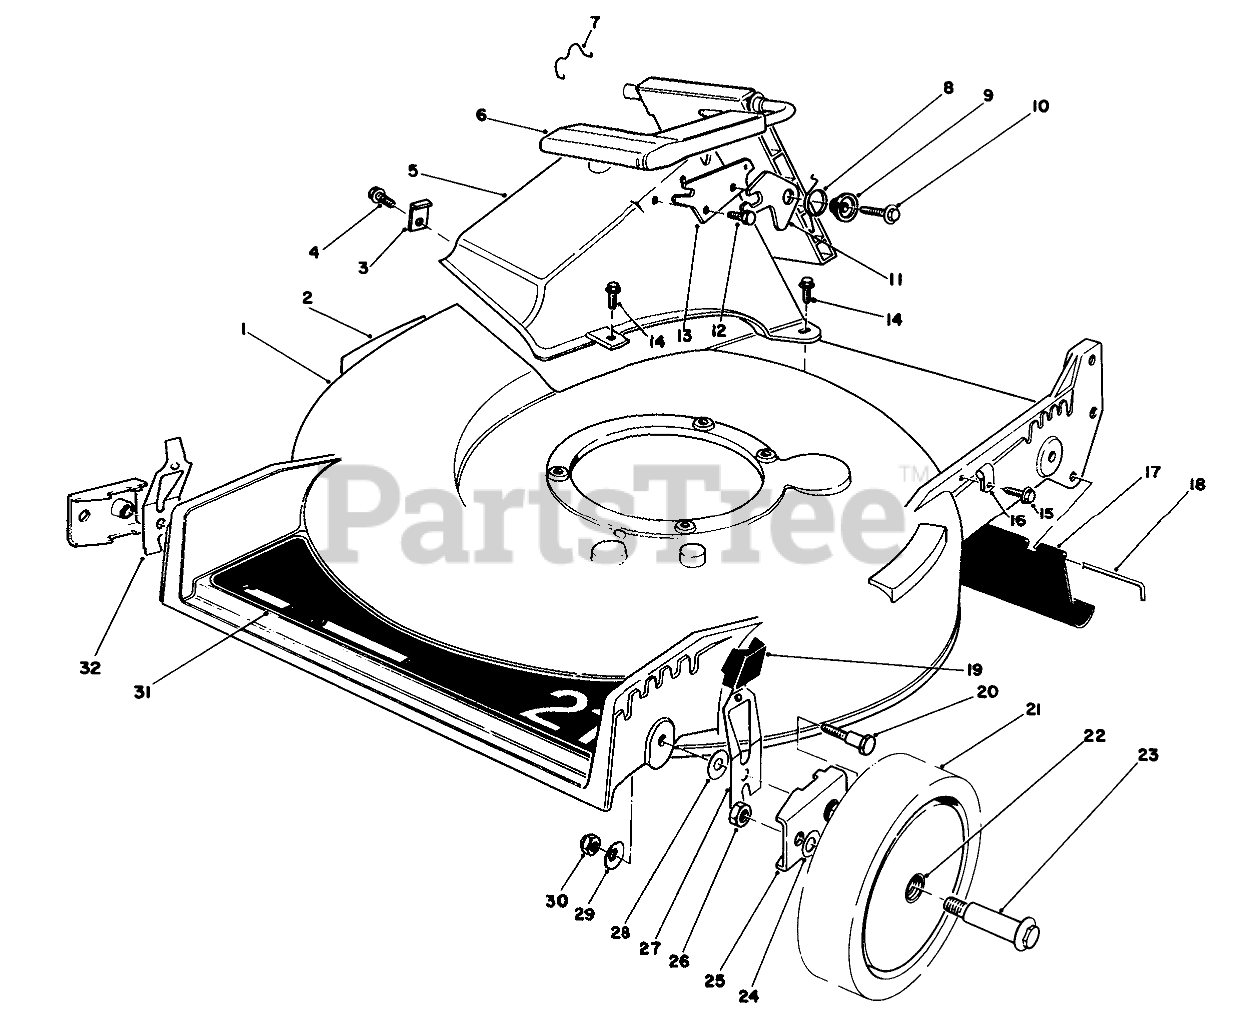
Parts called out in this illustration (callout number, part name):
1	21HP RB-SUZ HSG/DECAL
2	DECAL-DANGER
3	TUNNEL CLIP
4	SCREW
5	Tunnel Discharge
6	Discharge Door Assembly
7	DOOR RET SPRING
8	TORSION SPRING
9	DOOR SPACER
10	SCREW-HWH
11	SAFETY LATCH
12	SCREW-PLASTITE
13	DOOR LATCH PLATE
14	SCREW-HWH
15	SCREW
16	CLAMP-CABLE
17	SHIELD-TRAILING
18	ROD-SHIELD
19	KNOB-ARM
20	PIVOT SCREW
21	Wheel & Tire Assembly (Inc. Ref. #22)
22	BUSHING
23	BOLT-WHEEL
24	WASHER
25	HP PIVOT ARM ASM
26	Nut
27	L. HP SPRING ARM ASM
28	WASHER-PIVOT
29	WASHER-BELLEVILLE
30	NUT-LOCK, NI
31	DECK DECAL
32	R HP SPRING ARM ASM
